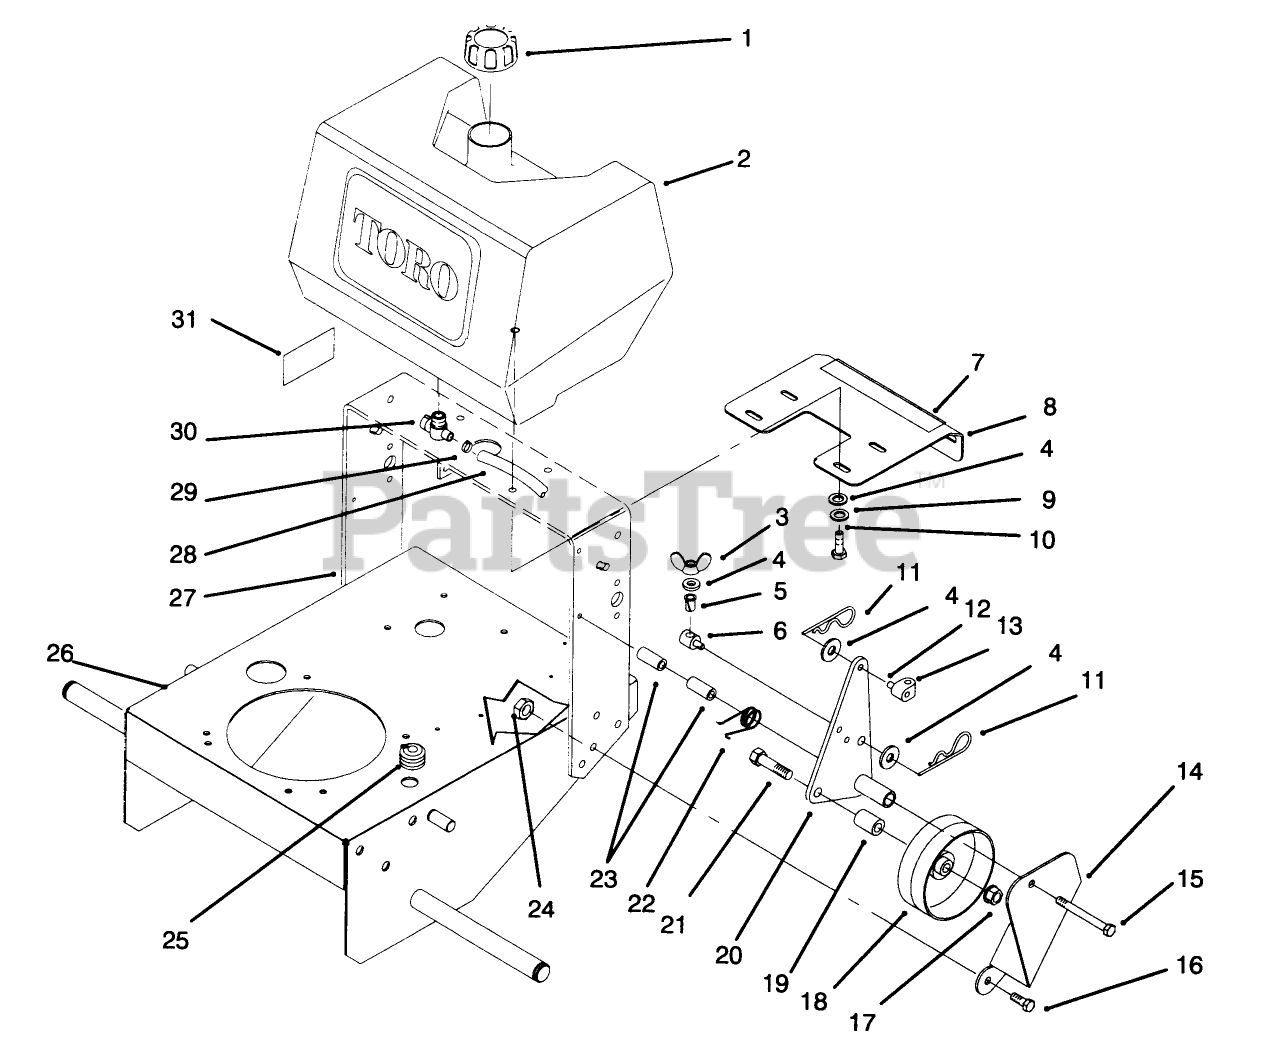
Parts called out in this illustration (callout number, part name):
1	GAS CAP ASM
2	FUEL TANK
3	NUT-WING
4	WASHER-PLAIN
5	BUSHING-NYLON
6	FITTING-ROD
7	DECAL-GROUND SPEED
8	Plate
9	WASHER-LOCK
10	SCREW-HH
11	PIN-COTTER
12	PIN-CLEVIS
13	FITTING-ROD
14	Bracket-LH
15	SCREW-HH
16	SCREW-HH
17	NUT-LOCK, NI
18	IdlerWheel
19	WHEEL IDLER SPACER
20	BRACKET-Idler, LH
21	SCREW-LEVELER
22	SPRING-TORSION, LH
23	SPACER-PIVOT, IDLER
24	NUT-LOCK, NI
25	GROMMET
26	Frame
27	Frame Rear
28	HOSE-FUEL
29	CLAMP-HOSE
30	VALVE-FUEL
31	DECAL-FUEL SHUT OFF
